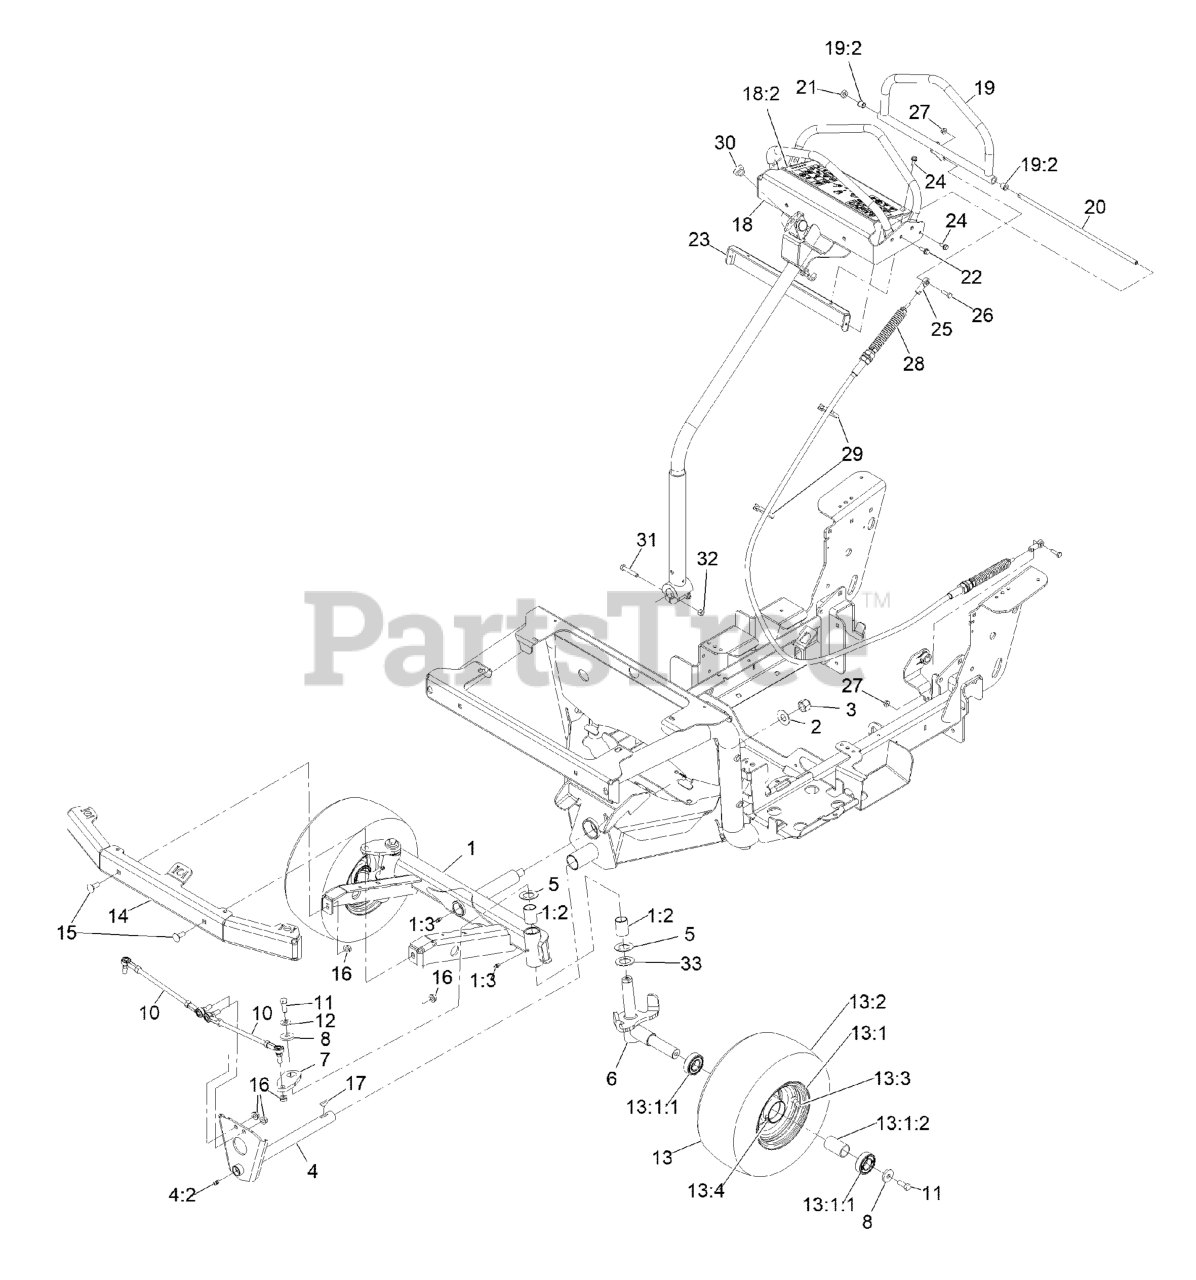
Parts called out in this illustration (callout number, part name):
1	FRONT AXLE ASM
1:2	BEARING-SLEEVE
1:3	ZERK-GREASE
2	WASHER-FLAT
3	NUT-HEX, NI
4	STEERING SHAFT ASM
4:2	ZERK-GREASE
5	WASHER-THRUST
6	FRONT AXLE ASM
7	ARM-STEERING
10	STEERING LINKAGE ASM
11	SCREW-HH
12	WASHER-BELLEVILLE
13	Wheel And Tire ASM
13:1	Wheel ASM
13:1:1	BEARING-BALL
13:3	Stem-Valve
13:4	FITTING-GREASE
14	BUMPER-FRONT
15	SCREW-CARR
17	KEY-WOODRUFF
18	Motion Handle ASM
18:2	DECAL-WARNING
19	Motion Handle ASM
19:2	BEARING
20	SHAFT-PIVOT, SPEED CONTRO
21	SPACER-SHAFT, DRIVE LEVER
22	SCREW-HHF
23	PANEL-REAR, STEERING
24	SCREW-HWH
25	ROD END-BALL JOINT
26	SCREW-HH
28	CABLE-MOTION
29	TIE-CABLE
30	BUMPER-RUBBER
31	Screw-HH
32	NUT-HEX
33	SPACER-RELIEF
